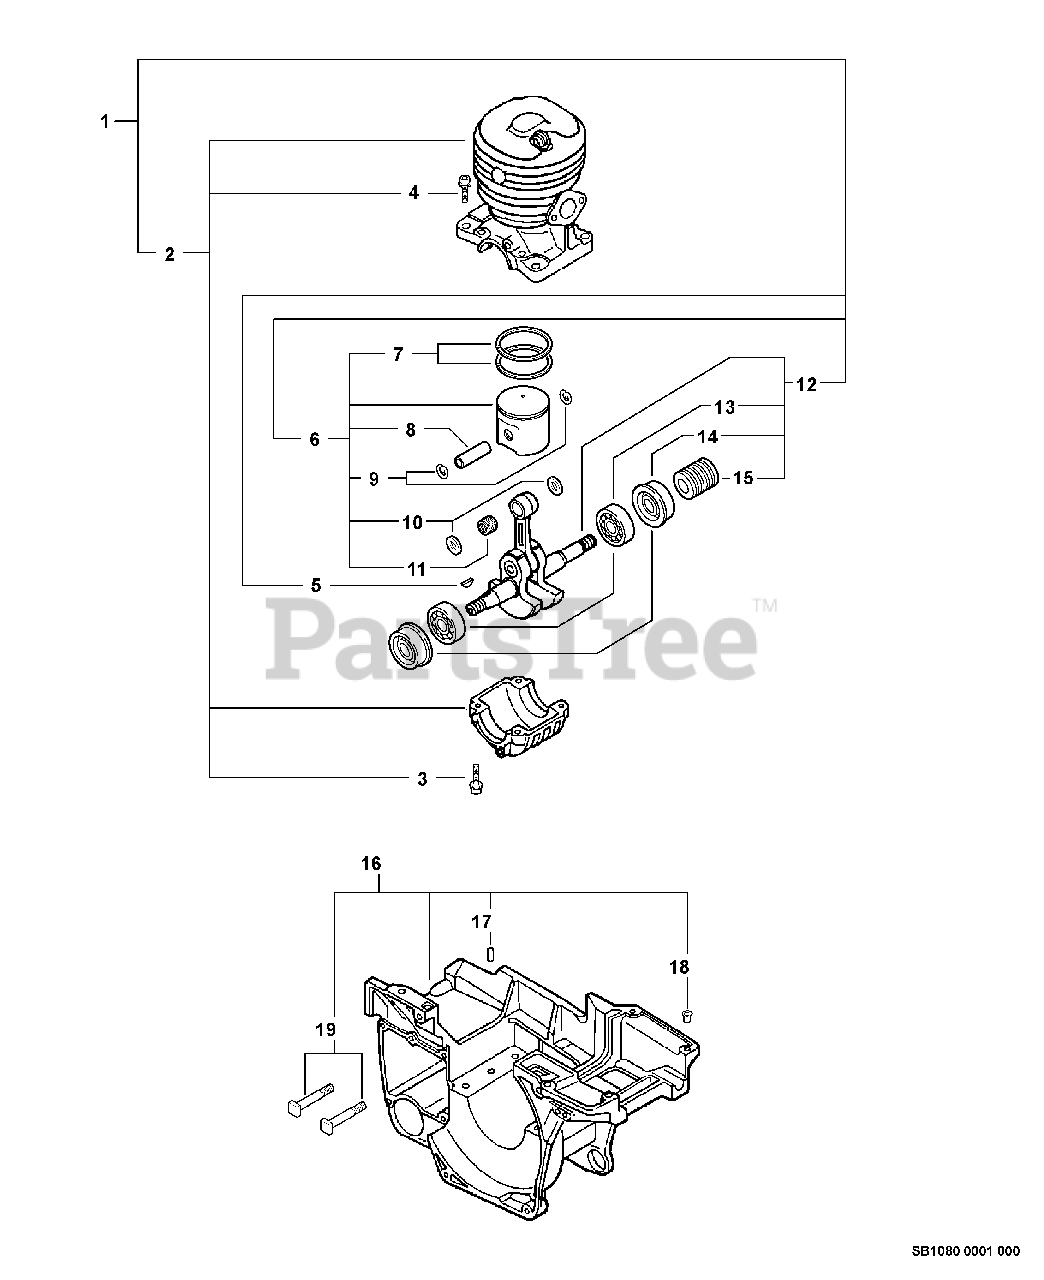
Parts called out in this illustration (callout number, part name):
1	SHORT BLOCK
2	CRANKCASE KIT
3	BOLT 5×20
5	KEY, WOODRUFF
6	PISTON KIT
7	RING, PISTON
8	PIN, PISTON
9	RING, SNAP
10	SPACER
11	BEARING, NEEDLE
12	CRANKSHAFT ASSY
13	BEARING, BALL 6202
14	SEAL, OIL
15	GEAR, WORM
16	COVER, ENGINE
17	PIN, LOCATING 4×8
18	COLLAR 5.5×6.65×5
19	STUD, GUIDE BAR 8
